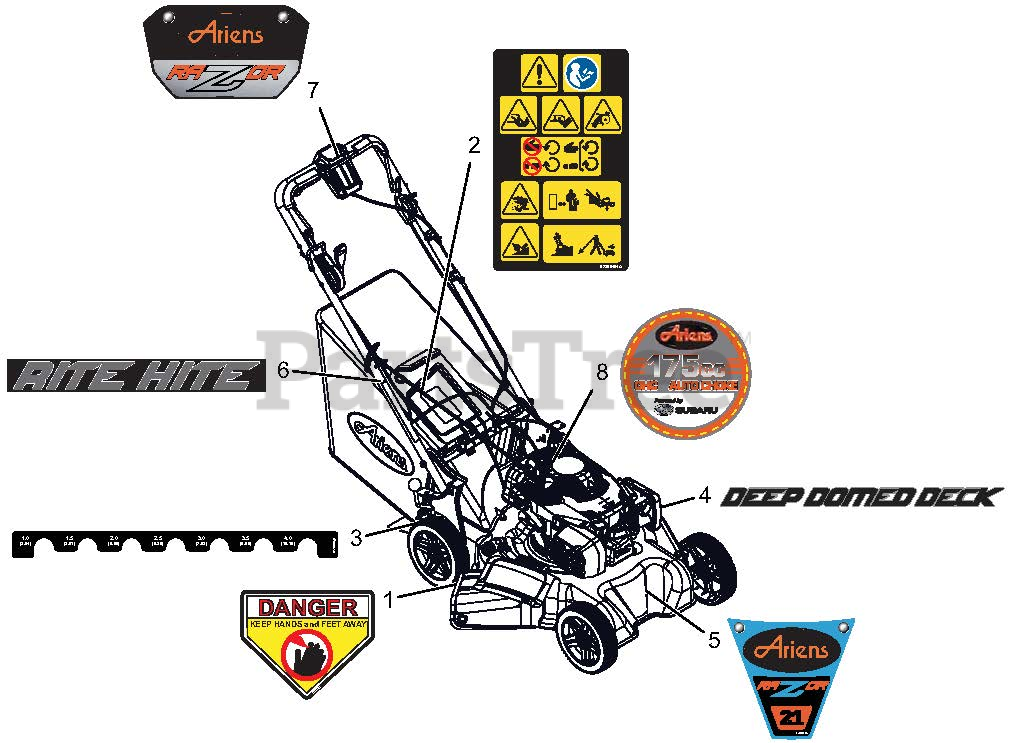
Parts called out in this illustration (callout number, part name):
1	DECAL, DANGER
2	DECAL,MAIN SAFETY_WAW LM
3	DECAL, HOC
4	DECAL, DEEP DOME DECK
5	DECAL, ARIENS RAZOR STYLE
6	DECAL, RITE HITE
7	DECAL, ARIENS RAZOR - SMALL
8	DECAL, ENGINE STYLE, ARIENS CE
